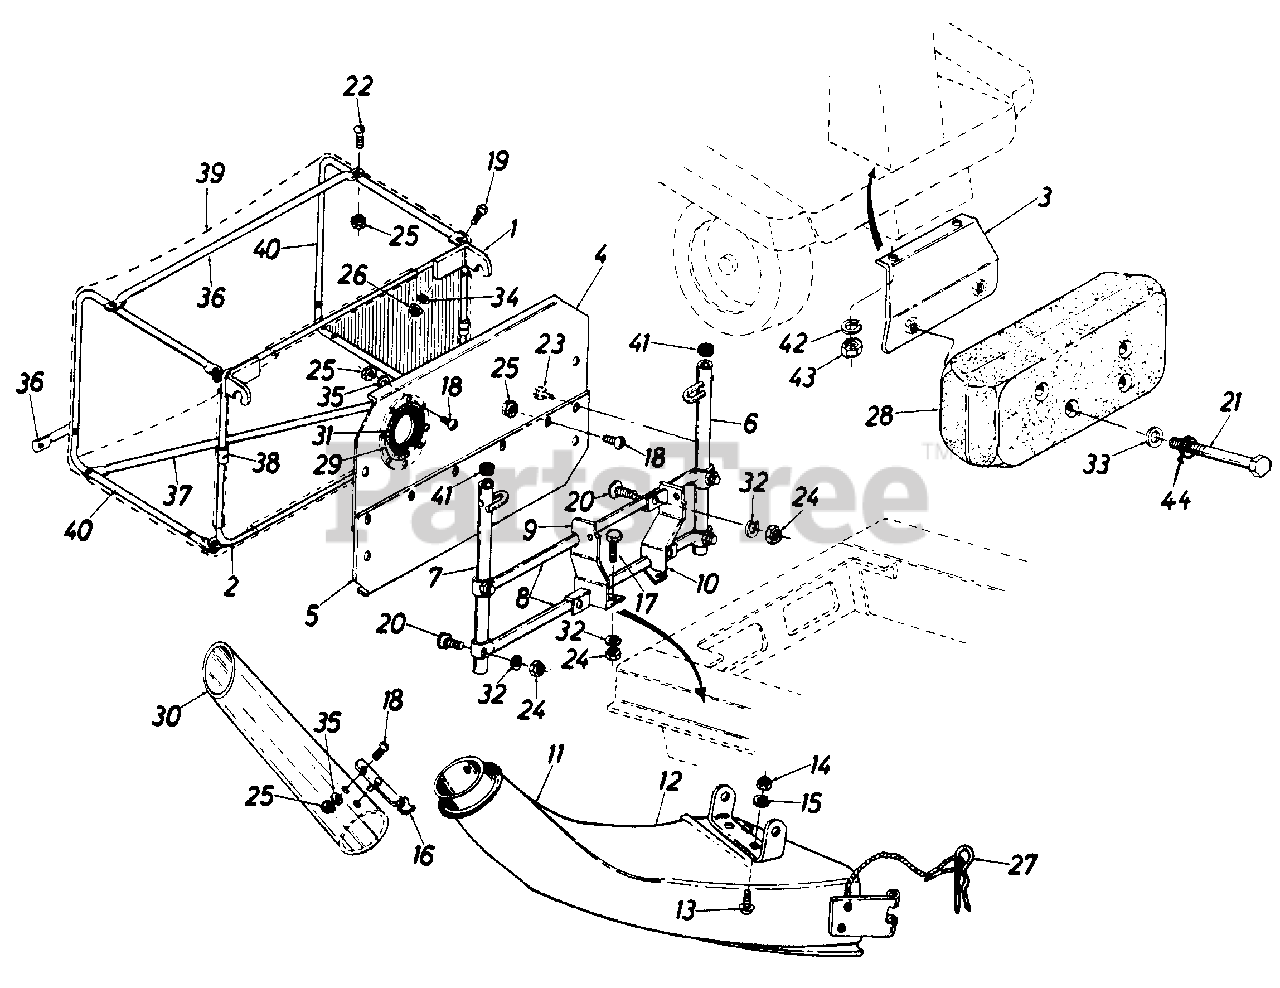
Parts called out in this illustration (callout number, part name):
1	Catcher Frame Ass y.-Upper
2	Catcher Frame Ass'y.-Lower
3	Counterweight Support Bracket. Ass'y.
4	Front Cover-Upper Half
5	Front Cover-Lower Half
6	L.H. Vertical Support Ass'y.
7	R.H. Vertical Support Ass'y.
8	Horizontal Support Tubing
9	Catcher Support Brkt. Ass'y.R.H.
10	Catcher Support Brkt. Ass'y.L.H.
11	Discharge Chute Ass'y.
12	Brkt. Chute Hinge
13	Carr. Bolt 1/4-20 x .62" Lg.
14	Hex Nut 1/4-20Thd.*
15	L-Wash. 1/4" I.D.*
16	Spring Lock Ass'y.
17	Hex Bolt 5/16-18 x .75" Lg. *
18	Truss Mach. Scr. #10-24 x .38" Lg. *
19	Hex Bolt 1/4-20x .62" Lg.*
20	Curved Carr. Bait 5/16-18 x 1.75" Lg.
21	Hex Bolt 3/8-16 x 4.50" Lg.*
22	Truss Mach. Scr. #10-24 x 1.0" Lg. *
23	Hex Wash. Hd. AB-Tap Scr. 1/4" x.62" Lg.
24	Hex Nut 5/16-18 Thd.*
25	Hex Sems Nut #10-24 Thd.
26	Hex Nut 1/4-20 Thd.*
27	Internal Coter Pin
28	Counter Weight-38#
29	Trim Strip-24"
30	Grass Chute Tube
31	Rubber Flap
32	L-Wash.5/16" I.D.*
33	FlatWasher3/8" I.D. x 1.25" O.D. x .17
34	L-Wash. 1/4" I.D.4
35	Fl-Wash. .203" I.D. x .41" O.D. x .040
36	Grass Catcher Handle
37	GrassCatcher Handle
38	Tubing Connector 1/2" I.D.
39	Grass Bag
40	Catcher Side Frame
42	L-Wash. 5/16" I.D.*
43	Hex Nut 5/16-18 Thd.*
44	Bell-Wash. 3/8" I.D. x 7/8" O.D.
